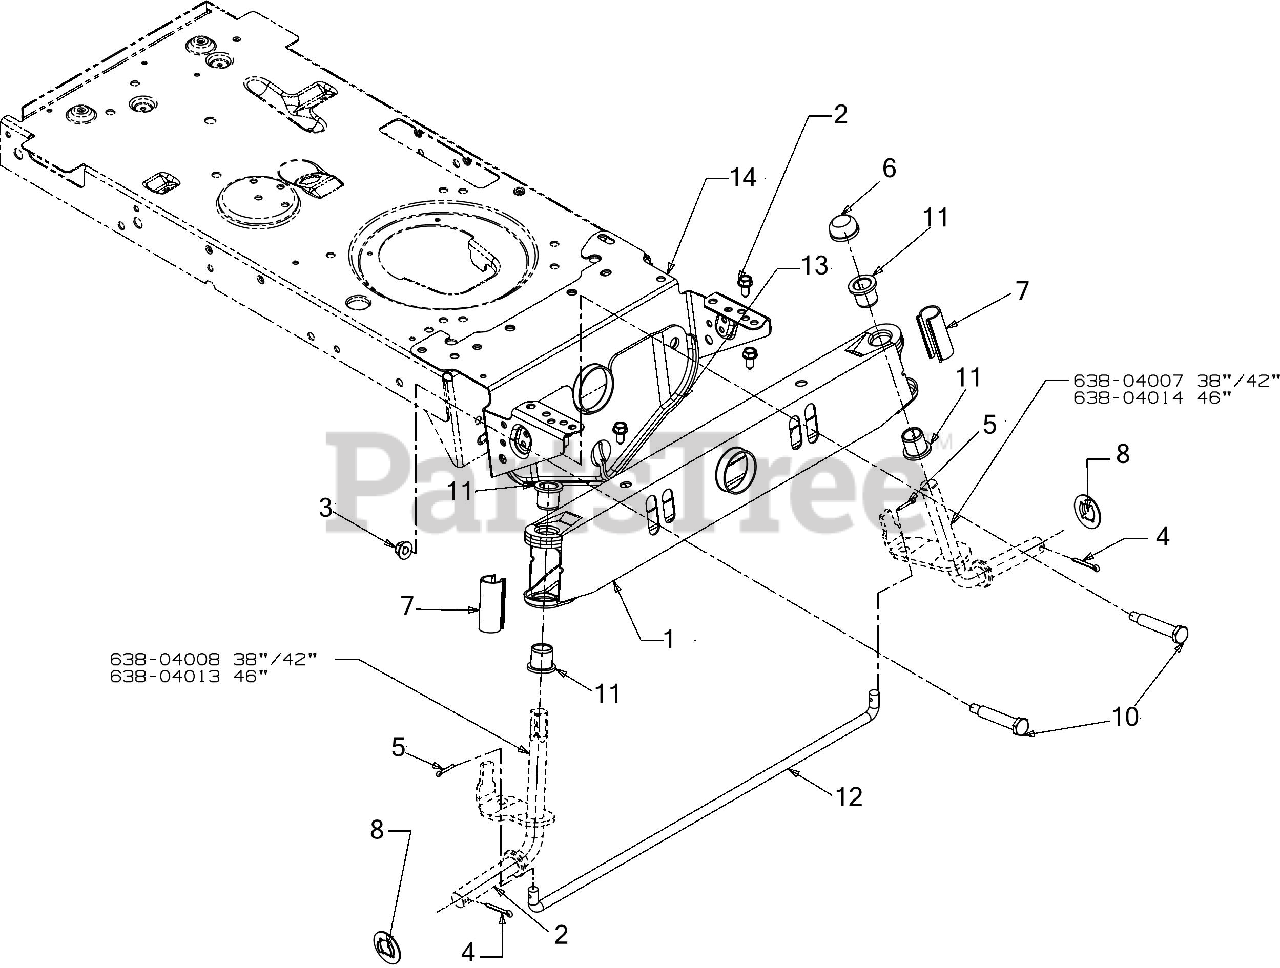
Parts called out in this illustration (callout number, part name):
1	PIVOT BAR
2	SCREW 5/16-18 x .750
4	COTTER PIN-5/32 DIA
5	COTTER PIN
7	AXLE CAP
8	FLAT WASHER .781 ID x1.590 OD
9	GREASE-#251 EP (NOT SERVICEABLE)
10	SHOULDER SCREW .500X2.38X3/8-16
11	FLANGE BEARING .760 ID
12	FIXED TIE ROD
13	DECK HANGER BRACKET
14	PIVOT BRACKET
